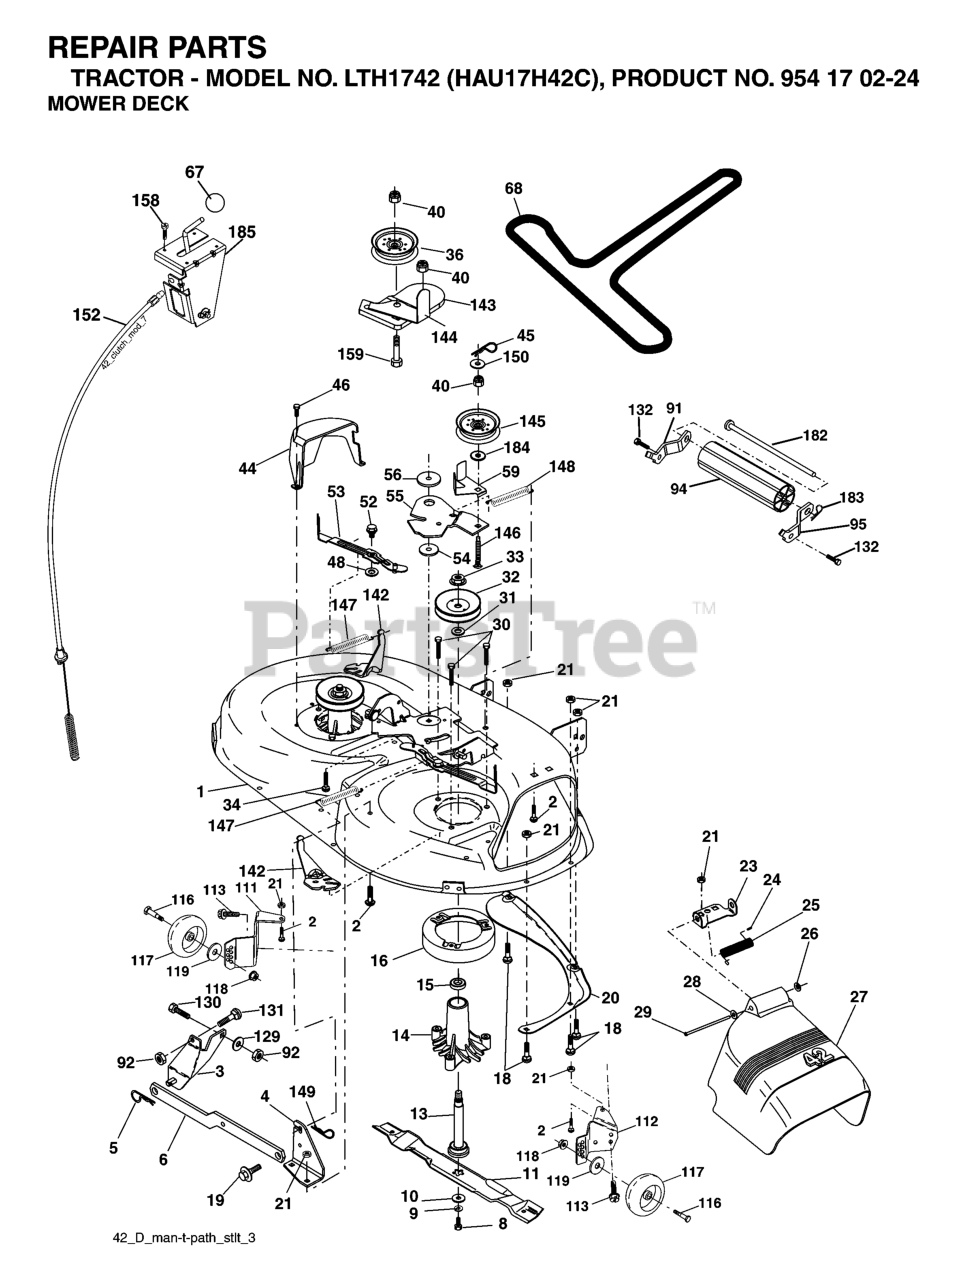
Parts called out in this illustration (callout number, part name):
1	42" DECK KIT
2	RP BOLT 5/16-18 X3/4 ZN/YEL GR
3	BRKT ASM SWAY BAR
4	BRACKET SWAY BAR 42" DECK
5	RETAINER-SPRNG RB
6	BAR SWAY DECK
8	BLADE BOLT
9	LOCKWASHER
10	WASHER.BLADE
11	42" HI-LIFT BLADE
13	SHAFT ASM VENT
14	HOUSING.MANDREL.VENTED (MACHD)
16	STRIPPER.MANDREL.ROUND.BLACK
18	BOLT
19	BOLT SHD 5/16-18
20	BAFFLE.VORTEX
21	LOCKNUT
23	BRKT, DEFL. MOWER
24	CAP-SLEEVE LT
25	SPRING TORSION
26	NUT PUSH M
27	SHIELD DEFLECTOR
28	Washer 11/32 x 5/8 x 16 Ga SD
29	ROD.HINGE
30	SCREW, WASHER HEAD
31	WASHER.SPACER.MANDREL
32	PULLEY/MANDREL
33	NUT, FLG TOPLOCK 9/16"
34	BOLT.3/8-16X1.50
36	FLAT IDLER PULLEY
40	NUT LOCK FLG 3/8-16 UNC
44	GUARD MANDREL LH BLACK
45	RETAINER M
46	SCREW.1/4-20X5/8
52	BOLT.SHOULDER.5/16-18
53	ARM BRAKE ASSY
55	ARM IDLER 42" MOWER LT/YT
56	SPACER.RETAINER.MOWER
59	GUARD, BELT
67	KNOB T (3/8 HOLE)
68	BELT V SECONDARY
91	BRACKET ASM NOSEROLLER LH
92	NUT
94	NOSE ROLLER
95	BRACKET ASM NOSEROLLER RH
111	BRACKET, WHEEL
112	BRACKET, WHEEL
113	BOLT.5/16HEX.WHS.HD
116	BOLT M
117	WHEEL.GAGE.HALF.SPOKED
118	LOCKNUT
119	WASHER.5/16.FLAT.STE.STD.
129	WASHER
131	BOLT D
132	SCREW, 3/8-16X3/4
142	ARM SPRING BRAKE MOWER
143	BRACKET, ARM IDLER
144	DNO KEEPER.BELT.42".CLUTCH.CBL
145	PULLEY
146	BOLT, CARRIAGE IDLER BLACK
147	SPRING EXTENSION
148	IDLER RETURN SPRING
149	SPRING.RETAINER.YELLOW.ZINC
152	CLUTCH CABLE 42"
158	SCREW
182	ROD ROLLER NOSE STANDARD
183	SPRING RETAINER
184	WASHER
185	HEAD ASM. CABLE CLUTCH
